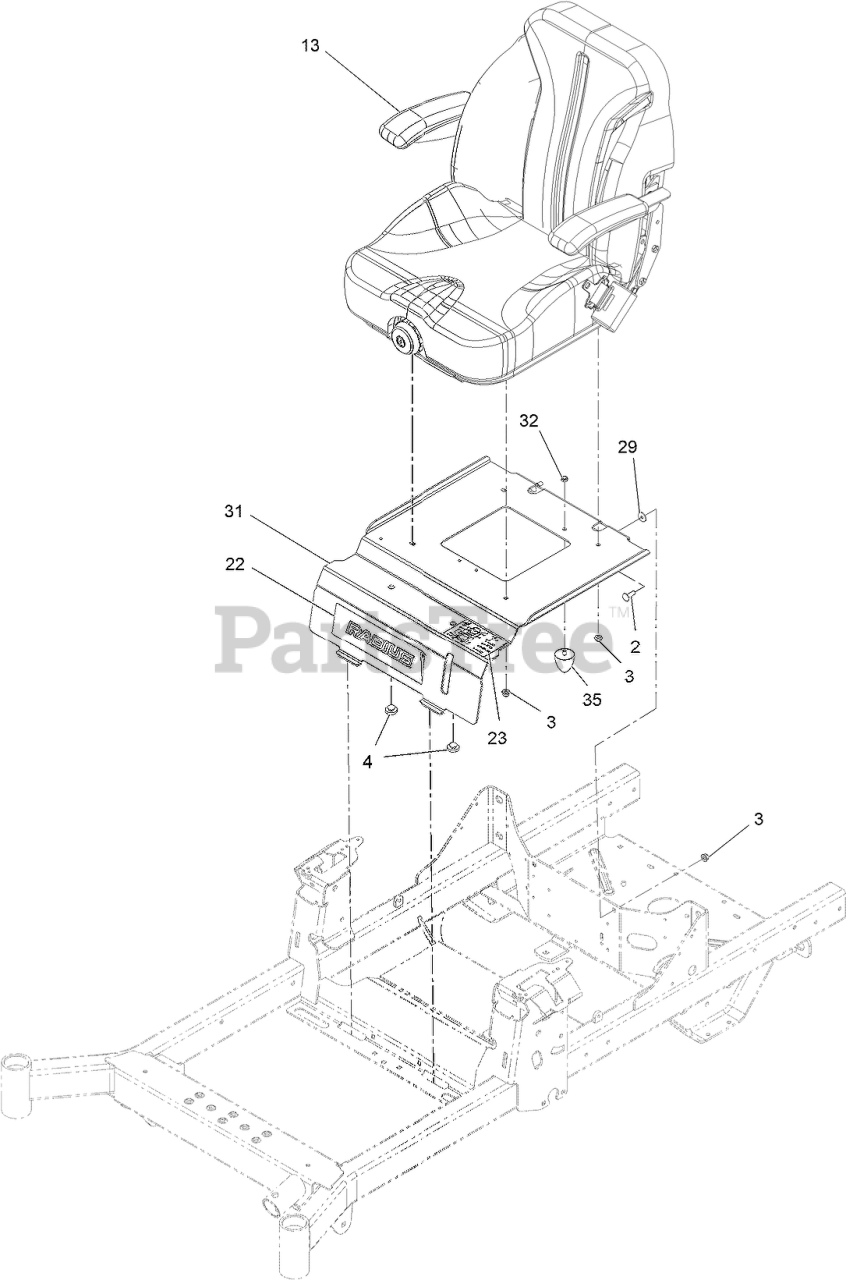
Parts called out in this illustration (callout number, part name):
2	SCREW-CARR
3	NUT-HF, NI
4	BUMPER-SEAT
13	ASM-SUSP SEAT
22	DECAL-RADIUS LOGO
23	DECAL-AID, SERVICE
31	PLATE-FIXED SEAT
32	NUT-LOCK, NI
35	BUMPER-RUBBER
